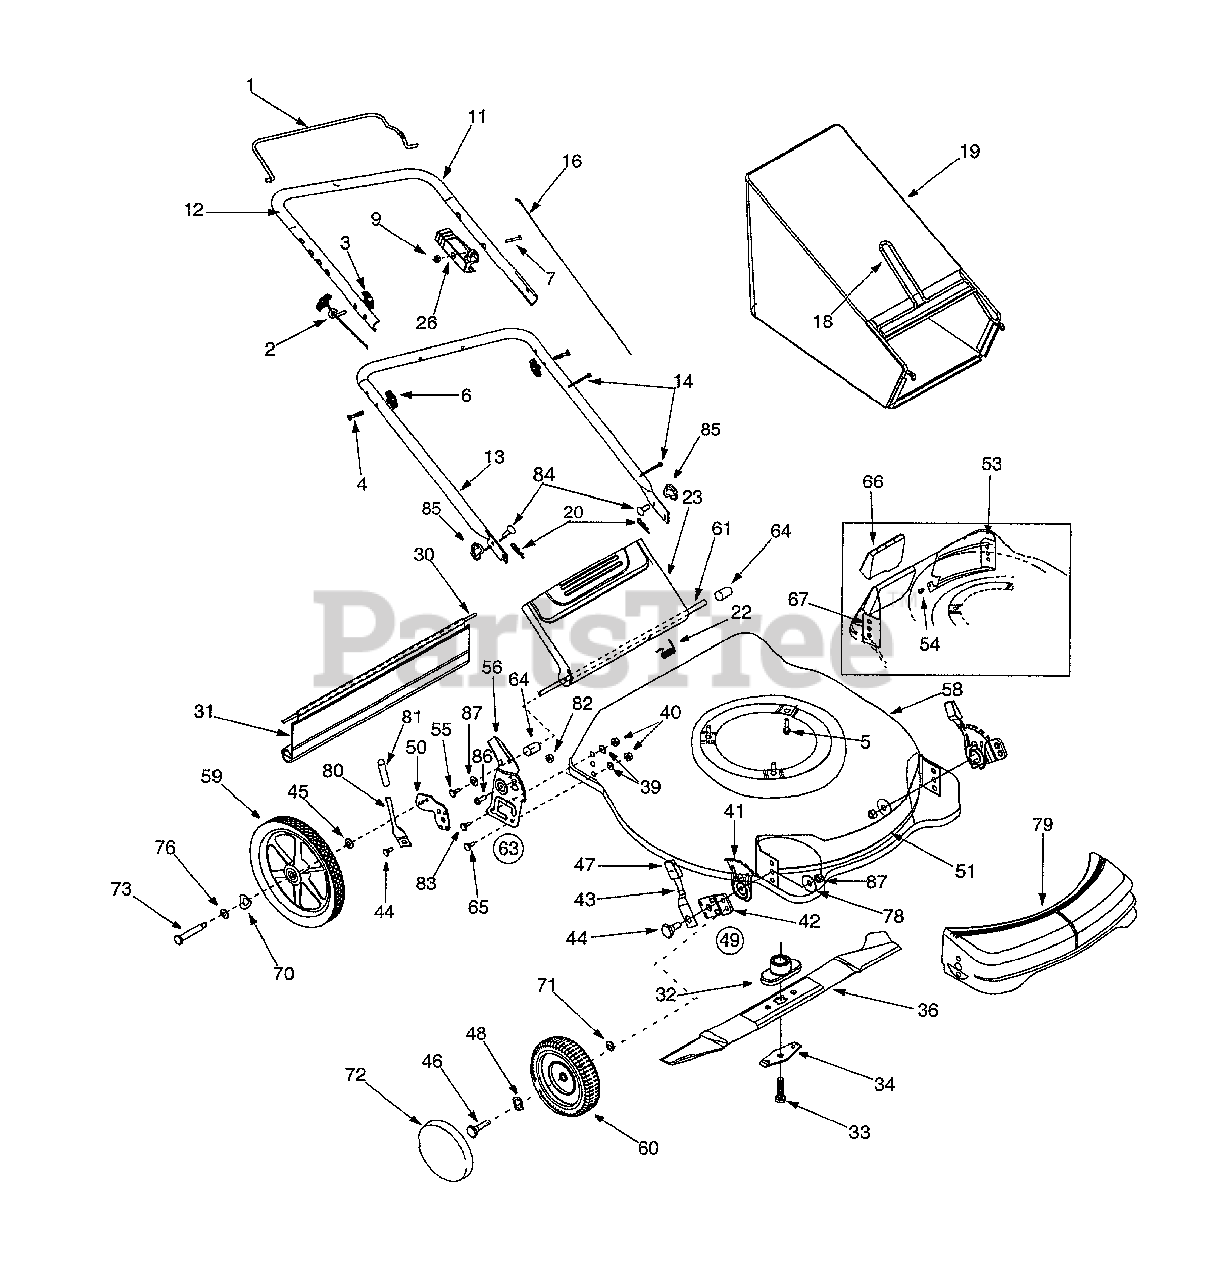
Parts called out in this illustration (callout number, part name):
2	Rope Guide
3	Handle Knob
4	Carriage Bolt 5/16-18 x 2"
5	Hex Washer Screw 3/8-16 x 1.00"
6	Hand Knob
7	C-Sunk Screw 1/4-20 x 1.3"
9	Hex Lock Nut 1/4-20
14	Cable Tie
16	Blade Control Cable - 44"
19	Grass Catcher Bag
20	Hairpin Clip
22	Door Spring
30	Wire Rod
31	Rear Flap
32	Blade Adapter
33	Hex Bolt 3/8-24 x 1.5
34	Blade Bell Support
36	21" Mulching Blade
39	Bell Washer .39 I.D. x 1.38 I.D.
40	Hex Nut 3/8-16
41	Height Adj. Plate
42	Pivot Bar
43	Front Wheel Spring Lever
44	Shoulder Bolt .5" x .357"
45	Bell Wash. .38" I.D. x .88" O.D.
46	Front Axle Bolt
47	Height Adjuster Knob
48	Wave Washer .510 x .750
49	Height Adjuster Assembly - R.H.
50	Pivot Bar - R. H.
54	Tap Screw 1/4-14 x .625.
55	Hew Washer Screw 1/4-20 x .500
60	Front Wheel Assembly 8 x 2
61	Chute Door Pivot Rod
63	Handle Bracket Assembly. - R.H.
64	Spacer .375 O.D. x .50 I.D. x 1.02"
65	Hex Cap Screw 3/8-16 x 1.0"
66	Rear Mulch Plug
70	Wave Washer
71	Spring Washer
72	Hub Cap
73	Rear Axle Bolt
76	Flat Washer
78	Bell Washer
79	Front End Cover
80	Spring Lever, Rear
81	Foam Grip
82	Hex Flange Lock Nut 3/8-16
83	Hex Washer Screw 1/4-14 x .625
84	Carriage Bolt 14-20
85	Wing Nut
86	Hex Scr. w/Washer 1/4-14 x .625"
87	Hex Nut 3/8-16
